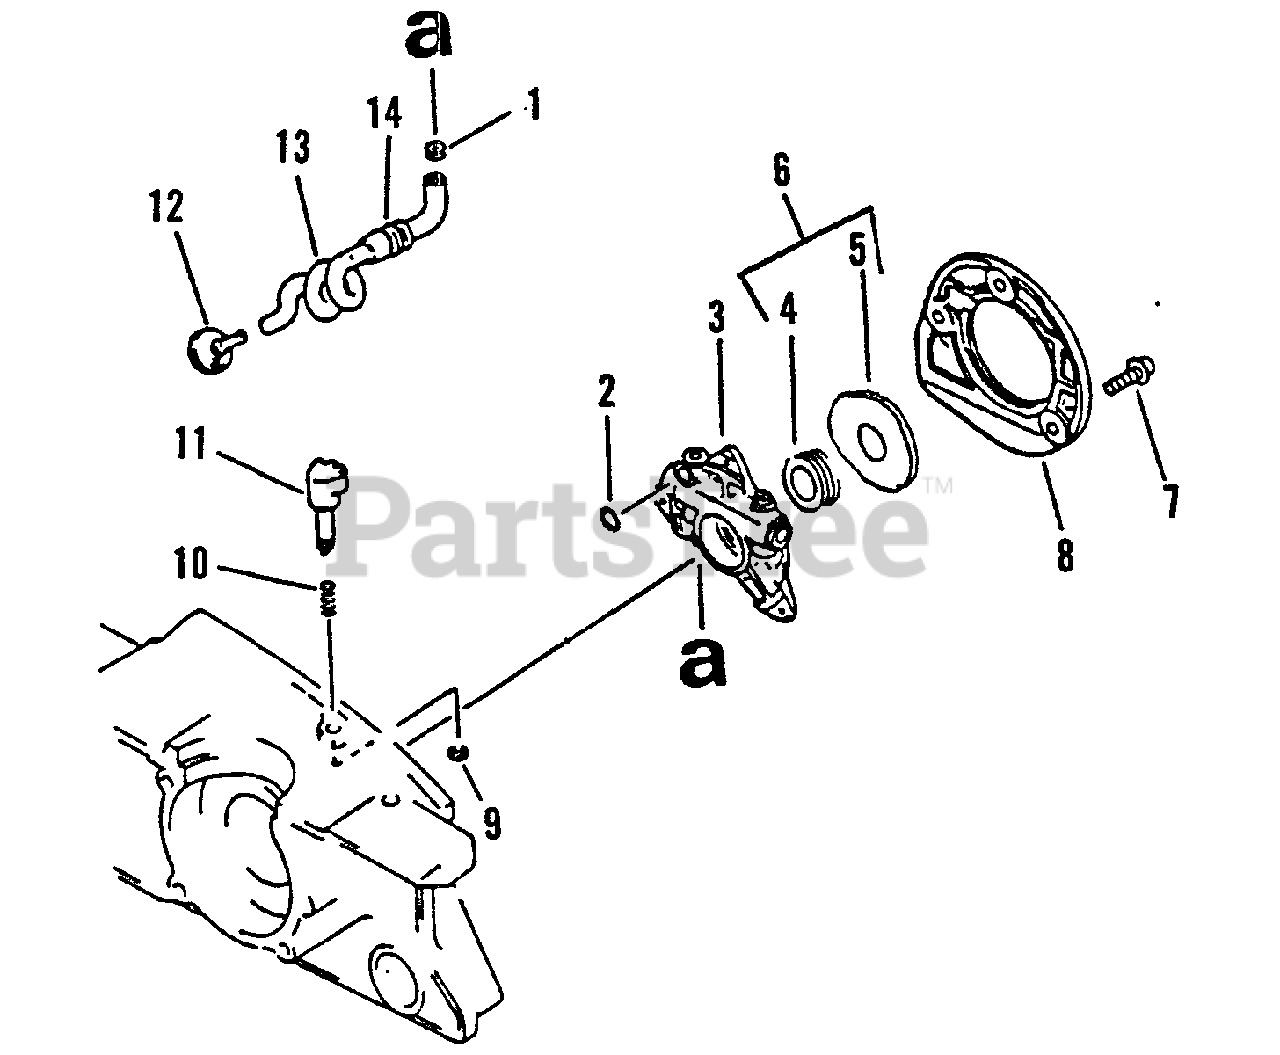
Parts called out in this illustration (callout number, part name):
1	CLIP Ø6.5 MM
2	O-RING 3
3	AUTO-OILER ASSY
4	GEAR, WORM
6	GEAR, WORM
7	SCREW 4×14
8	COVER, OIL PUMP - GRAY
9	E-RING 3
12	FILTER, OIL
13	PIPE, OIL
